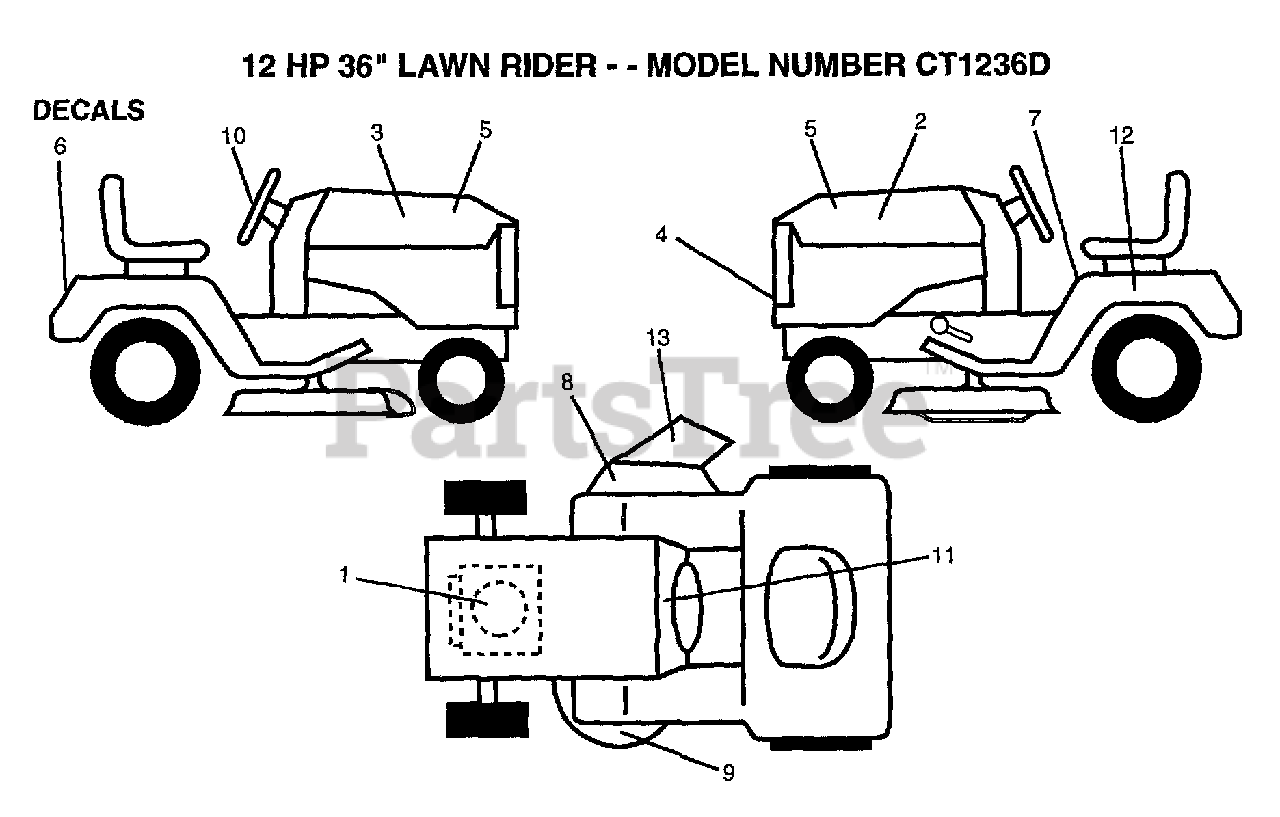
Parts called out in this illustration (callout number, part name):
1	DECAL.B&S.272129
2	"DECAL,STP HD LH"
3	"DECAL,STP HD RH"
4	GRILL DECAL
5	"DECAL,HOOD"
6	FENDER DECAL
7	DECAL
8	DECAL WARNING
9	DECAL YT
10	"DECAL,STR WHL"
12	DECAL
13	DECAL WARNING
